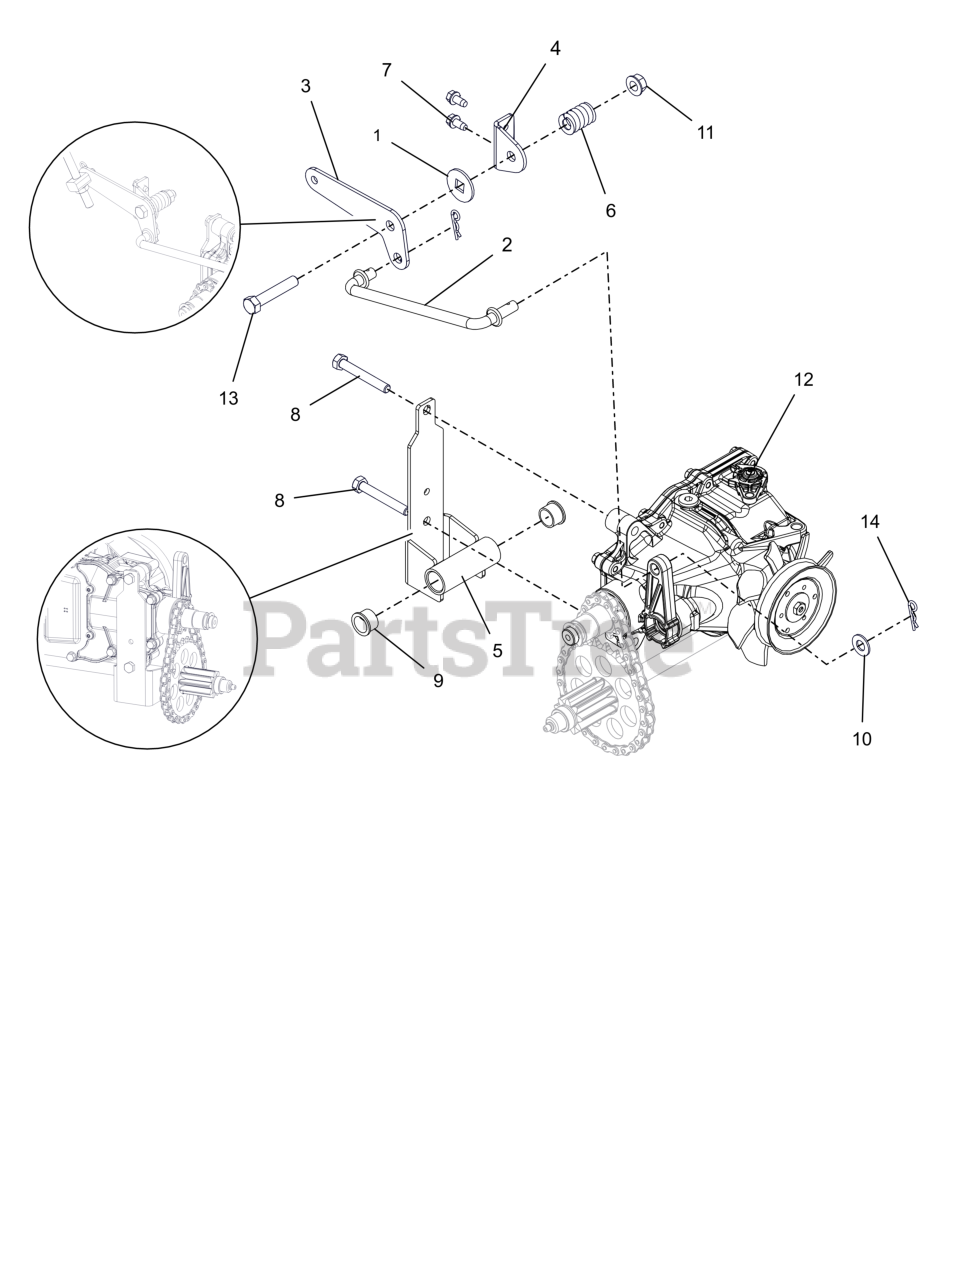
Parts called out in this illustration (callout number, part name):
1	FRICTION WASHER
2	ROD, HYDRO TRANS SHIFT
3	PIVOT, HYDRO TRANS SHIFT
4	BRACKET, HYDRO SHIFT PIVOT
5	TRANS MOUNT, TENSIONING, WHEEL
6	SG-COMP .187X.56X1.62
7	SCR-TAP .25-20X.50 HWH ZCC
8	BLT, HEX .31-18X2.25 G5 ZCC
9	BSHG-FLG .625X.750X.500X.875
10	WSHR,FLT .406X.812X.065 ZCC
11	NUT-LK-TOP-FLG .38-16 ZC120
12	TRANSMISSION, HYDROSTATIC
13	BLT,HEX .38-16X2.00 G5 ZCC
14	PIN, HAIR #213 .08X1.19 ZCC
